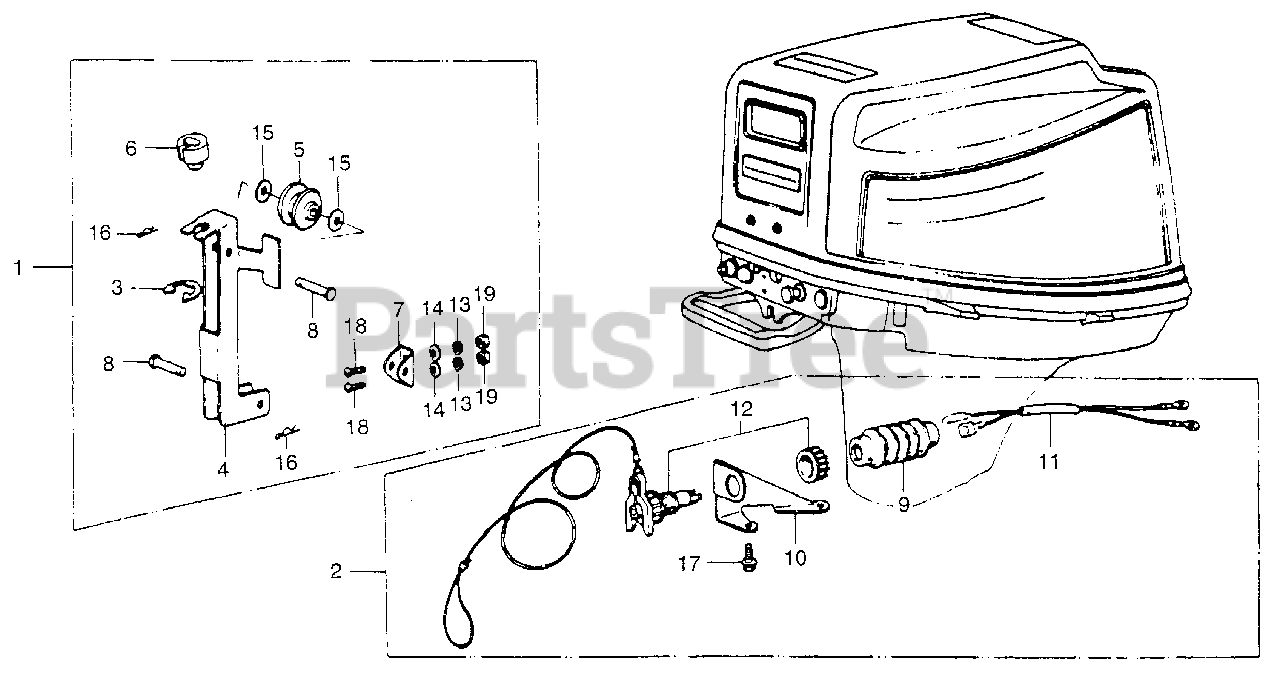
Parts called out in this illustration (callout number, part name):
1	STARTER KIT, VERTICAL (N/A: SEE COMPONENTS)
2	SWITCH KIT, SAFETY
4	STAY, VERTICAL STARTER
5	IDLER, VERTICAL STARTER
6	GUIDE, ROPE
7	BRACKET, VERTICAL STARTER
8	PIN, VERTICAL STARTER
9	RUBBER, SEALING
10	STAY, SAFETY SWITCH
11	WIRE B, SWITCH
12	SWITCH ASSY., EMERGENCY
12	SWITCH, SAFETY
13	WASHER, SPRING (6MM)
14	WASHER, PLAIN (6MM)
15	WASHER (10MM)
16	PIN, LOCK (10MM)
17	BOLT, HEX. (6X12)
18	SCREW, PAN (6X12)
19	NUT, HEX. (6MM)
